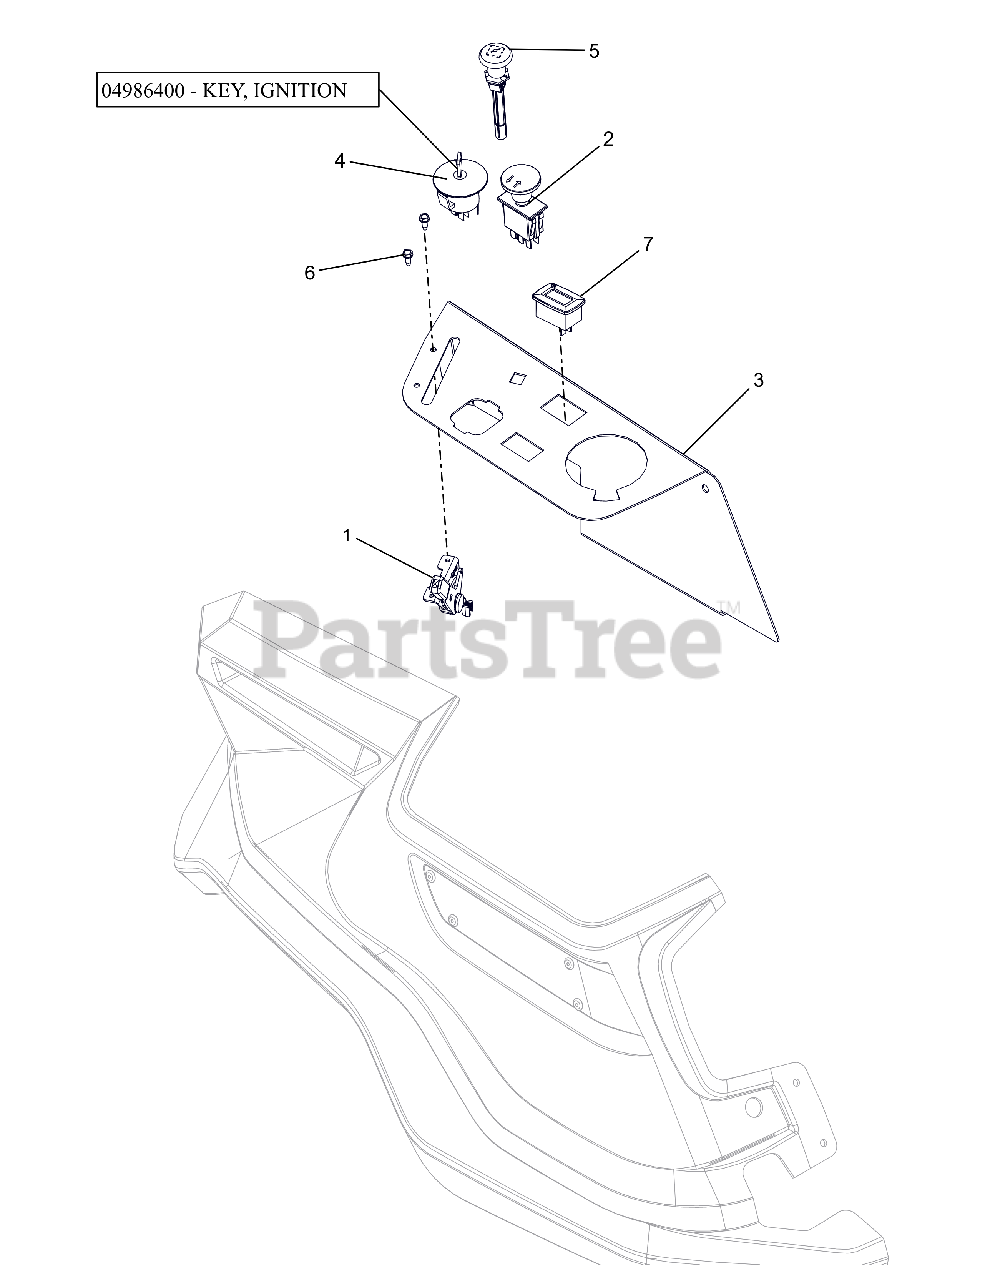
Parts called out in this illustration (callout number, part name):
1	CABLE - THROTTLE CONTROL
2	SWITCH, CLUTCH (YELLOW)
3	PANEL, RIGHT SIDE FENDER MOUNT
4	KEYSWITCH-IGNITION 4 POS
4	KEY, IGNITION
5	CABLE - CHOKE, SNAP-IN
6	SCR,TAP #10-24X.50 HWH TR ZCC
7	METER, HOUR W/MAINTENANCE
